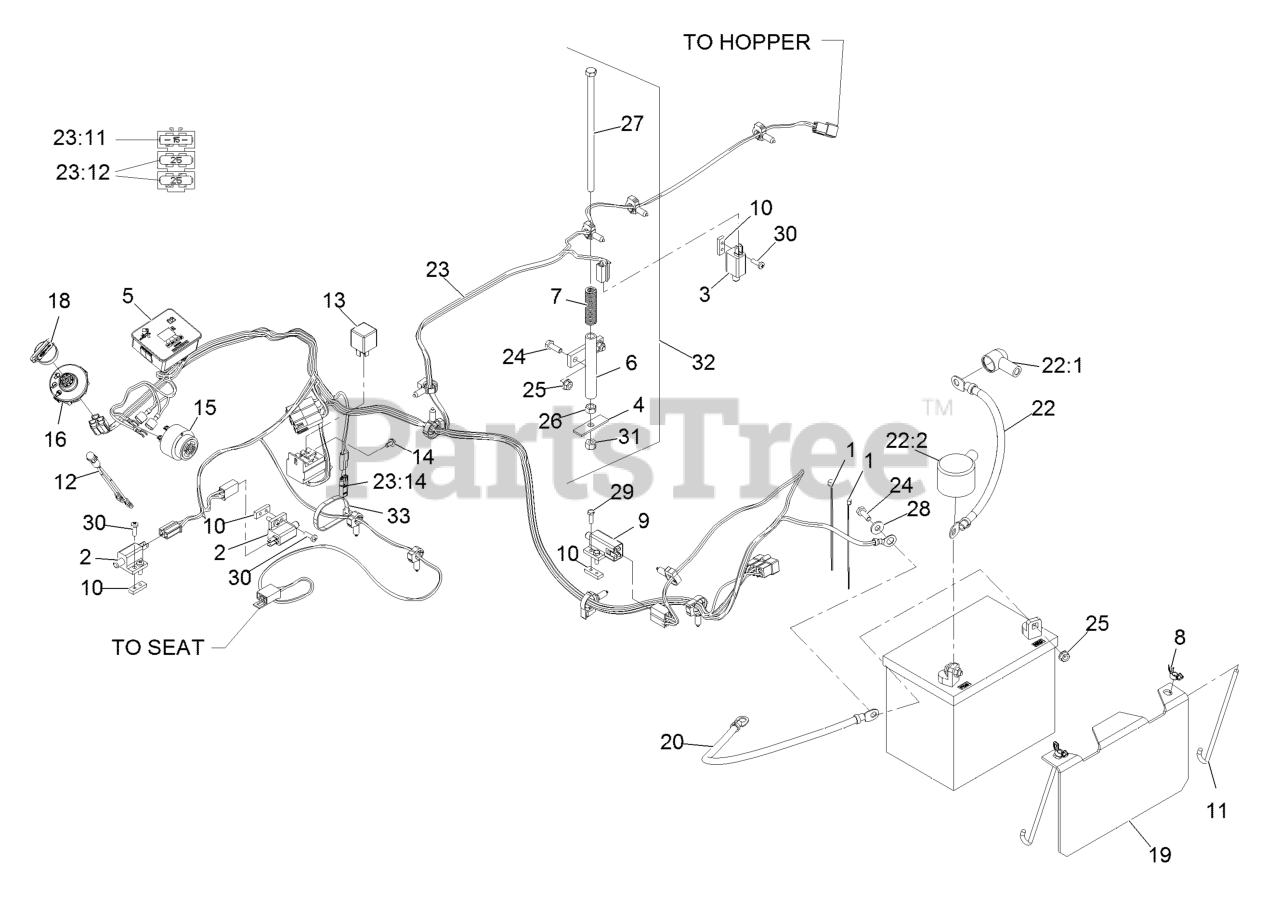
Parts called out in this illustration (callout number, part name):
1	TIE-CABLE
2	SWITCH-OPEN, NORMALLY
3	SWITCH-CLOSED, NORMALLY
4	PLATE-SWITCH, SEAT
5	HOUR METER ASM
6	MOUNT-SPRING, SEAT
7	SPRING-SWITCH, SEAT
8	WINGNUT
10	PLATE-TAPPED
11	BOLT-HOLDDOWN
12	INDICATOR-LED, RED
14	SCREW-HWH
15	ALARM-TONE, DUAL
18	KEY-IGNITION
19	HOLD DOWN-BATTERY
20	CABLE-BATTERY, NEGATIVE
22	CABLE-BATTERY, POSITIVE
22:1	INSULATOR-SOLENOID
22:2	INSULATOR-BATTERY
23	HARNESS-WIRING
23:11	FUSE-BLADE, 15 AMP
23:12	FUSE-BLADE, 25 AMP
23:14	CAP-PLUG
24	SCREW-HH
26	NUT-HEX
27	SCREW-HH
28	WASHER-FLAT
30	SCREW-PPH
31	NUT-LOCK, NI
32	HOPPER SWITCH ACTUATOR AS
33	TIE-PLASTIC
